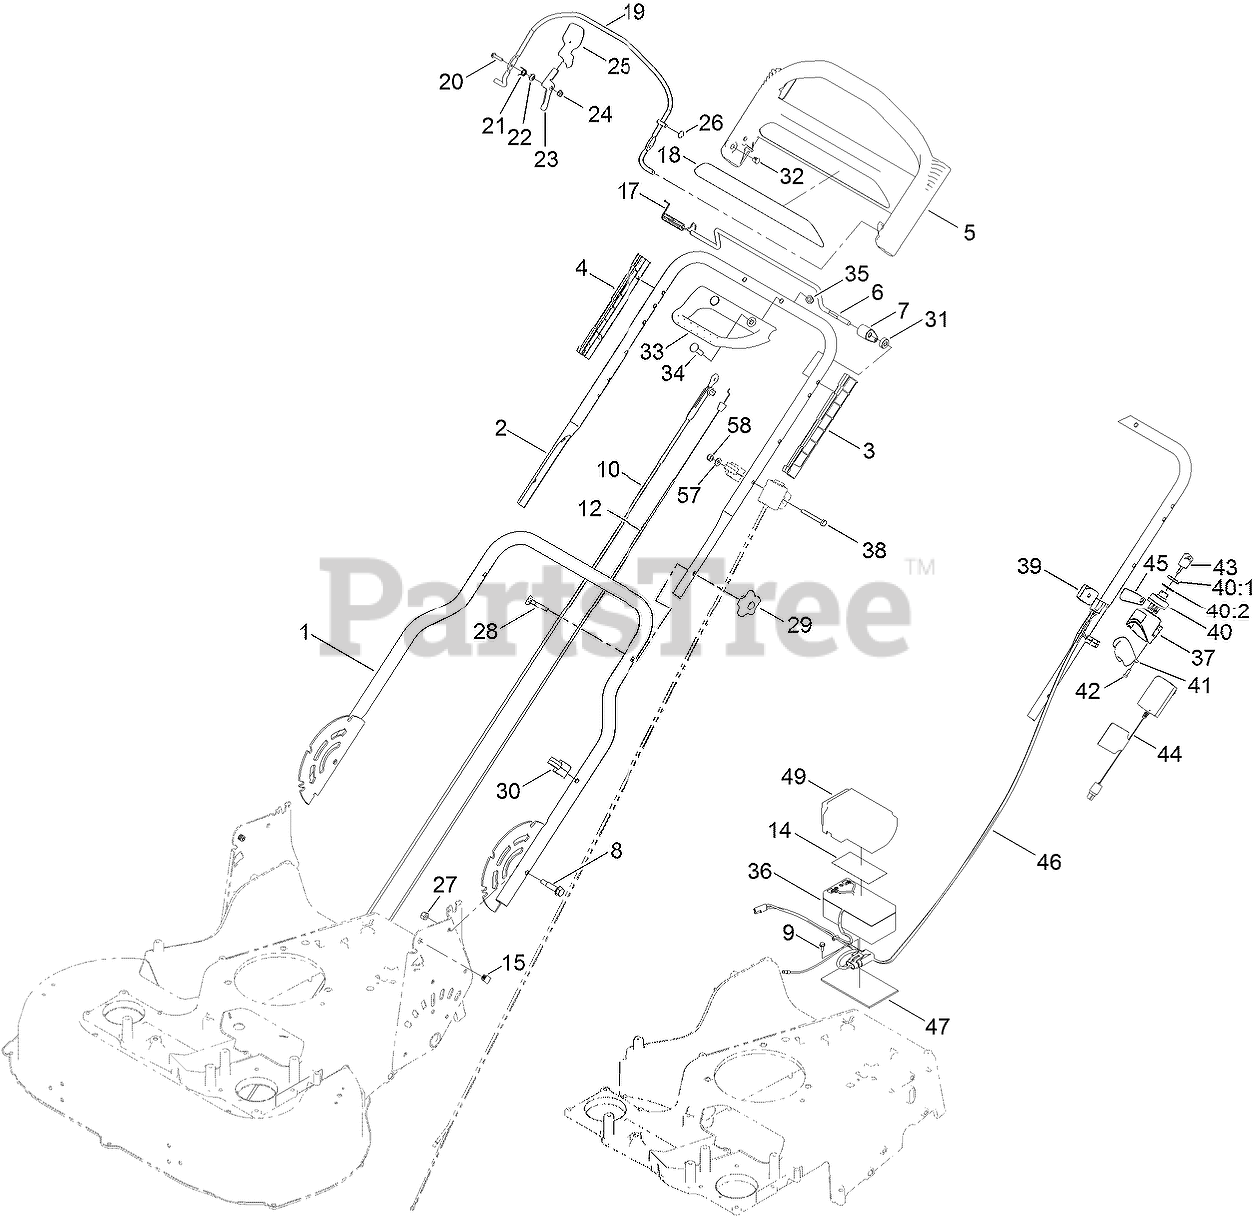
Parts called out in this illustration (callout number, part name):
1	HANDLE-LOWER
2	HANDLE-UPPER
3	GUIDE-LH
4	GUIDE-RH
5	HANDLE-CONTROL
6	BAR-CONTROL, TRACTION
7	LEVER-TRACTION
8	BOLT-SHOULDER, HHF
9	SCREW-TAPTITE
10	CABLE-BRAKE
12	CABLE-TRACTION
14	DECAL-WARNING
15	PLUG-SQUARE
19	BAIL-BRAKE
20	SCREW-HWH
21	SPRING-TORSION
22	SPACER
24	NUT-LOCK, FLANGE
26	NUT-SPEED
27	NUT-LOCK, NI
28	SCREW-HANDLE
29	KNOB-HANDLE
30	GUIDE-CABLE
31	SPACER
32	PLUG-DOME
33	HANDLE-ASSIST, TRACTION
34	BOLT-CARRIAGE
35	NUT-ACORN
36	BATTERY-WET
37	HOUSING-SWITCH, KEY
38	SCREW-HH
39	ANCHOR-CABLE, UPPER
40	SWITCH-STARTER
40:1	NUT-HH
40:2	WASHER-LOCK
41	COVER-SWTCH
42	SCREW-PPH
44	CHARGER, BATTERY (12V)
45	DECAL-SWITCH, IGNITION
46	HARNESS-WIRE
47	FOAM-BATTERY
49	COVER-BATTERY
57	WASHER-FLAT
58	NUT-LOCK, NI
